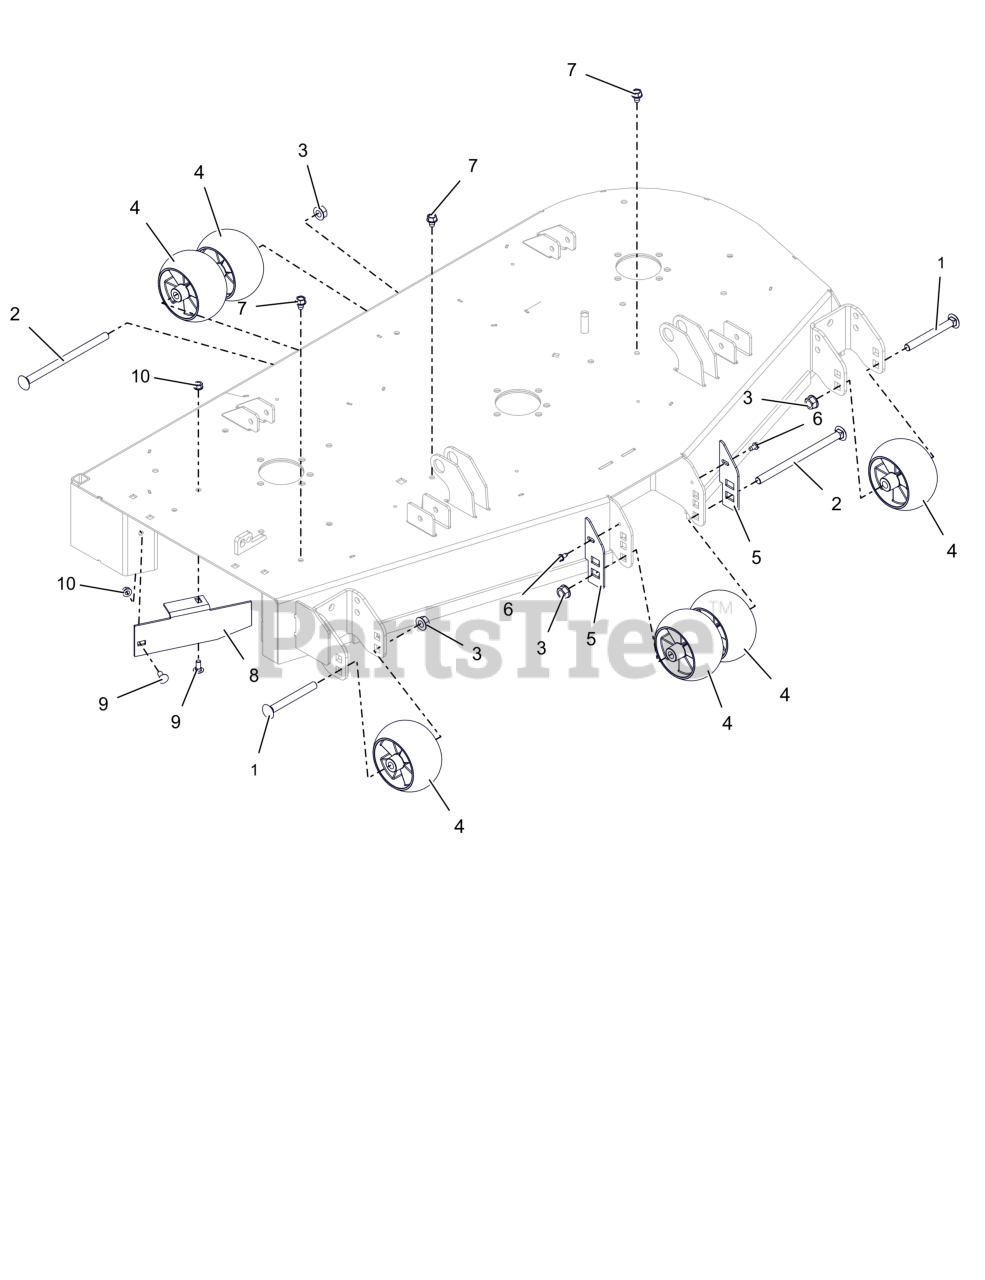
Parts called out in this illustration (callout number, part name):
1	BOLT, RHNS .50-13X4.50 G5 ZCC NS
2	BOLT, RHNS .50-13X8.00 G5 ZCC NS
3	NUT-LK-CTR-FLG .500-13 GG ZCC
4	WHEEL, ANTI SCALP - 5X3 CTR W/RIBS
5	PLATE, ANTI SCALP WHEEL 60" (ORANGE)
6	SCR-TAP .25-20X.50 HWH ZCC
7	SCR,TAP .375-16X.50 HWH TR ZCC
8	BAFFLE, DISCHARGE, 52"
9	BLT,RHSN .31-18X.75 G5 ZCC
10	NUT,LK-CTR-FLG .31-18 GF ZCC
